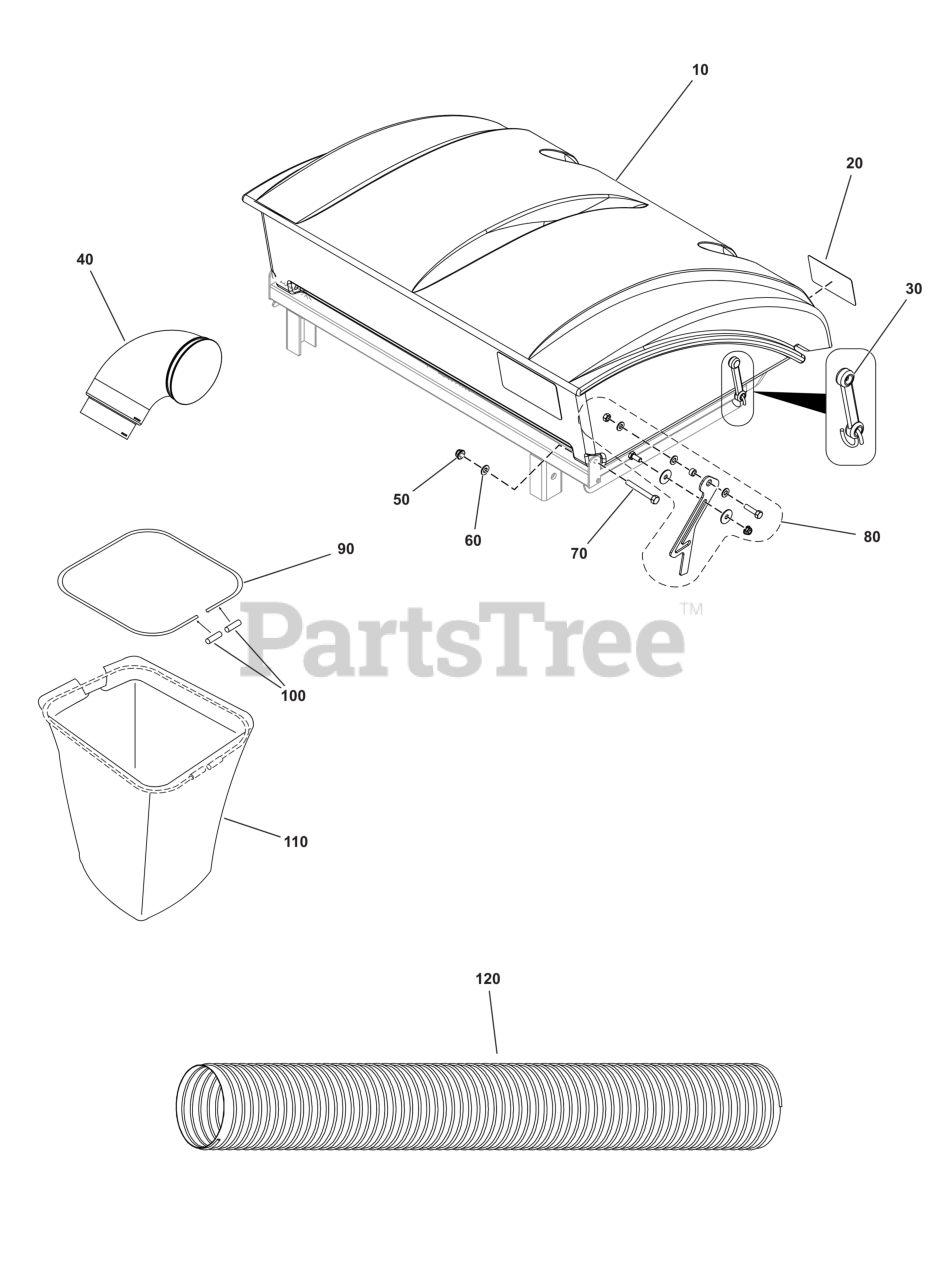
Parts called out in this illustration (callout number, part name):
10	TOP ASSEMBLY / P2B+ / FERRIS - NET
20	RED REFLECTOR DECAL - NET
30	RUBBER STRAP W/HOOKS - NET
60	WASHER, 1/2" SAE
70	BOLT, 1/2-13 X 2-1/2
80	VAC KIT HW / P3B / FERRIS - NET
90	PART B0227 BAG RING / GENERIC - NET
100	PART J0274 VINYL CAP - NET
120	CONNECTOR-TUBE
